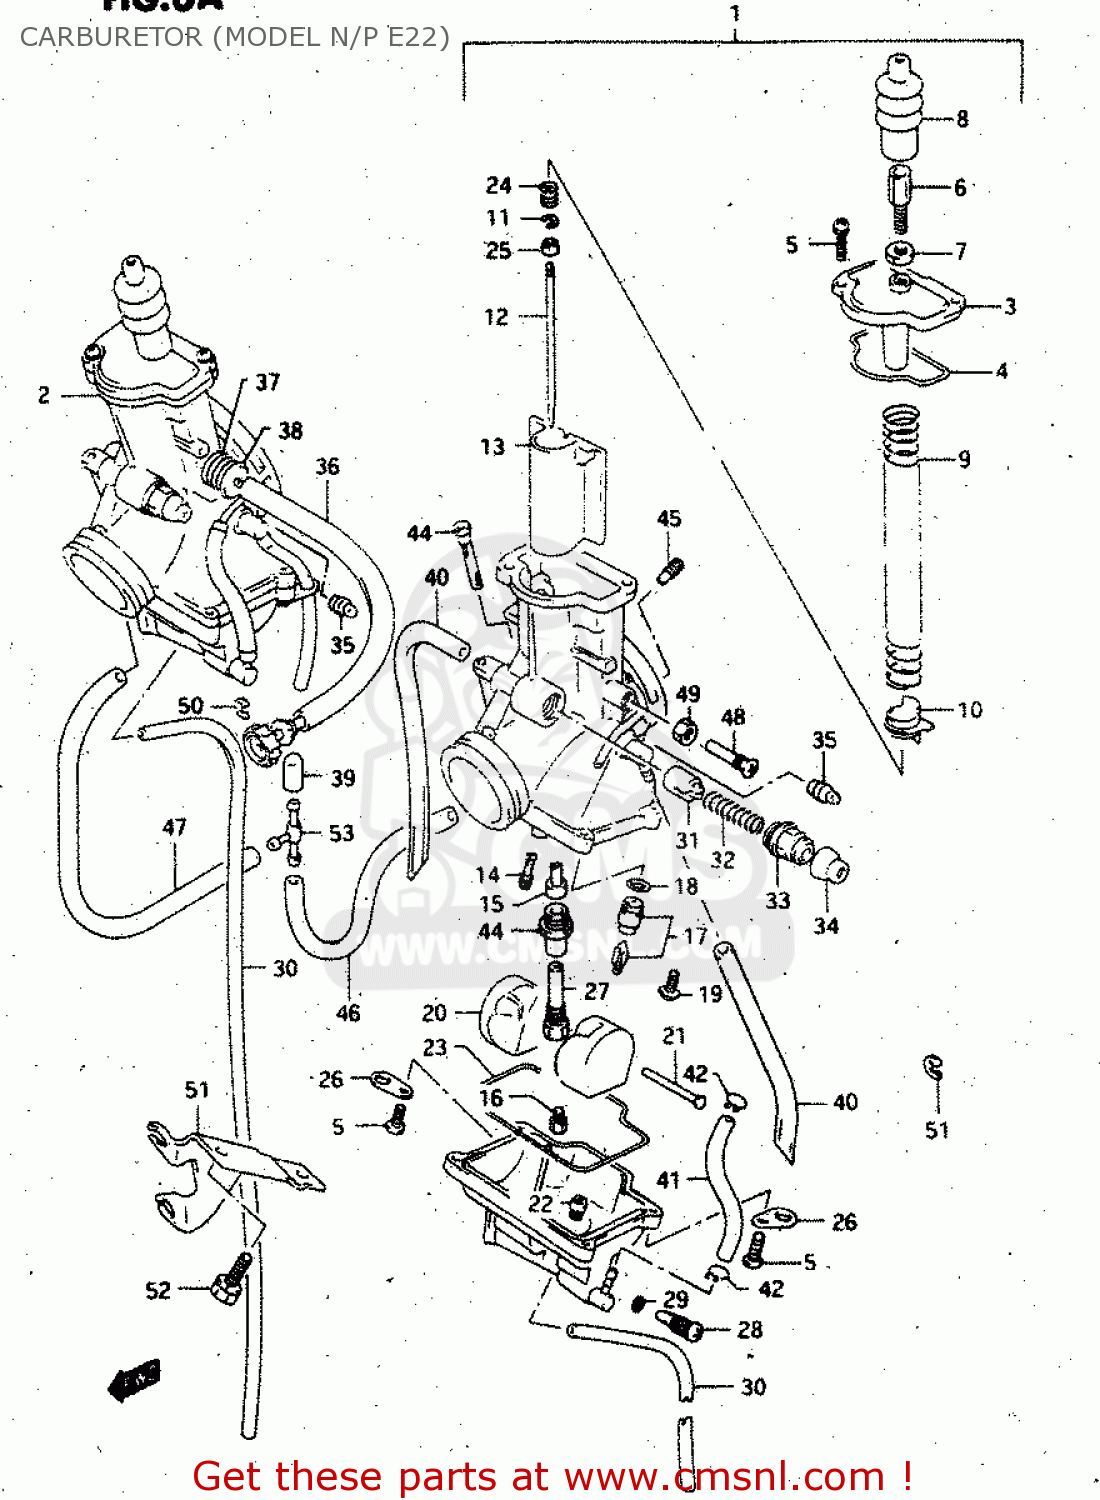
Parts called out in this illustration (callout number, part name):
1	CARBURETOR ASSY, LH
2	CARBURETOR ASSY, RH
3	CAP, TOP
4	O RING,TOP CAP
5	SCREW
6	ADJUSTER,CABLE
7	NUT
8	CAP,CABLE ADJUSTER
9	SPRING
10	RING
11	CLIP,NEEDLE
12	NEEDLE, JET LH (6FL89-55-3)
13	VALVE, PISTON (CA:1.5)
14	JET,PILOT(22.5)
15	JET,NEEDLE
16	JET,MAIN(270)
17	VALVE ASSY,NEE
18	O-RING,NEEDLE VALVE
19	SCREW
20	FLOAT
21	PIN,FLOAT
22	JET(45)
23	GASKET,FLOAT CAHMBER (NAS)
24	SPRING
25	RING
26	PLATE,CARBURETOR
27	HOLDER, JET
28	PLUG,DRAIN
29	O RING
30	HOSE(3X5X650)
31	PLUNGER,STARTER
32	SPRING
33	HOLDER,GUIDE
34	CAP
35	CAP
36	ADJUSTER,THROTTLE STOP
37	SPRING
38	WASHER
39	CAP
40	HOSE
41	HOSE SET
42	CLIP
43	RING
44	FILTER
45	JET,AIR(0.6)
46	HOSE
47	HOSE
48	SCREW,ADJUSTER
49	NUT
50	E RING
51	BRACKET,ADJUSTER
52	BOLT
53	3-WAY
